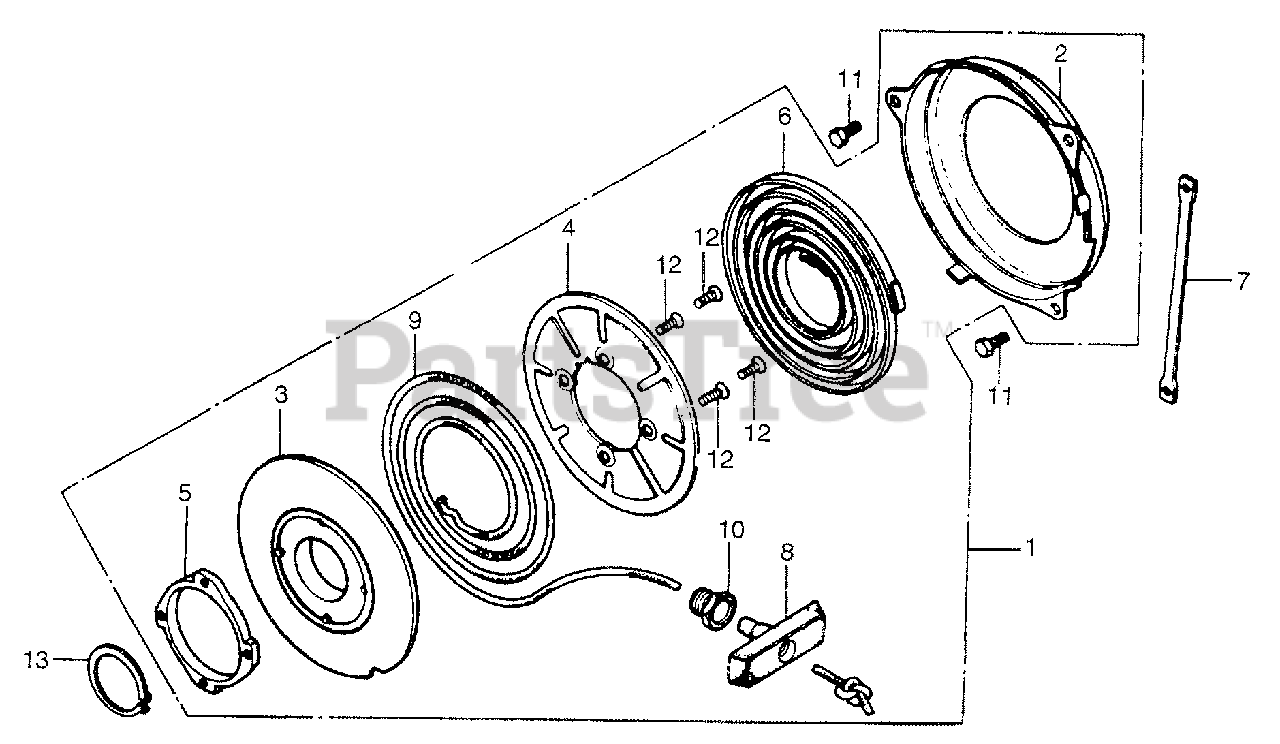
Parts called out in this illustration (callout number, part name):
1	STARTER ASSY., RECOIL (NOT AVAILABLE)
2	CASE, SPRING (NOT AVAILABLE)
3	PULLEY, STARTER
4	PLATE, STARTER (NOT AVAILABLE)
5	RATCHET, STARTER (NOT AVAILABLE)
6	SPRING, STARTER RETURN (NOT AVAILABLE)
7	SPRING, STARTER PULLEY SETTING (NOT AVAILABLE)
8	GRIP, STARTER (NOT AVAILABLE)
9	ROPE, STARTER (#5.5X79")
10	GUIDE, ROPE (NOT AVAILABLE)
11	BOLT, HEX. (5X10)
12	SCREW, FLAT (5X14)
13	CIRCLIP, OUTER (30MM)
